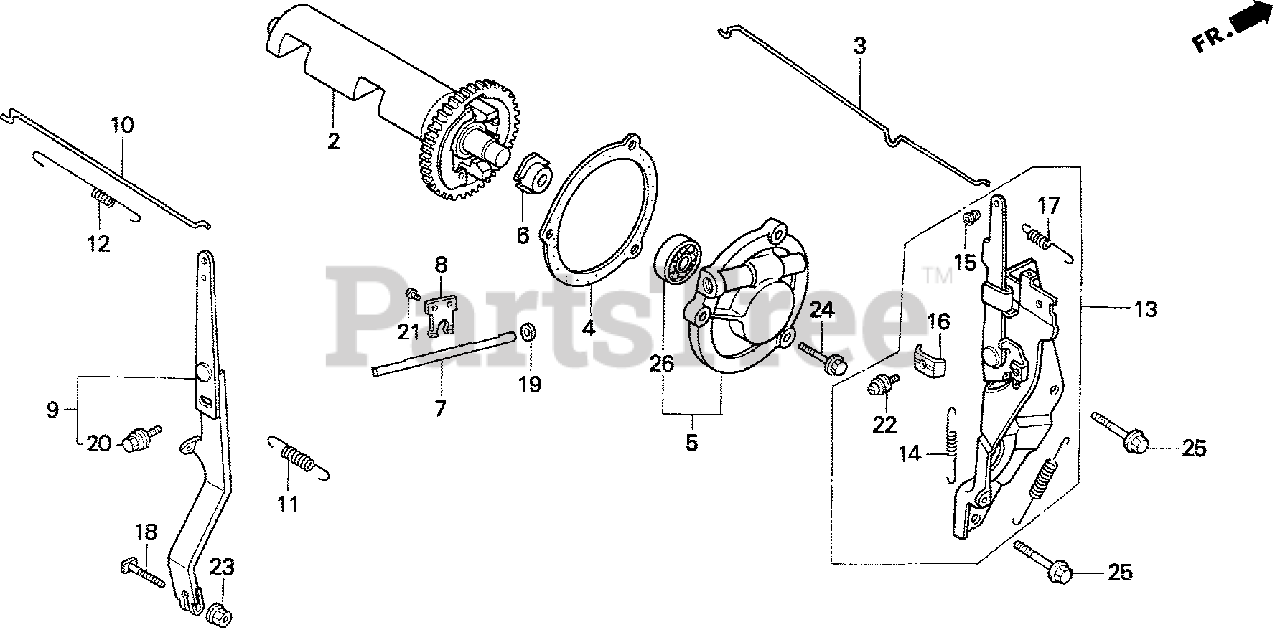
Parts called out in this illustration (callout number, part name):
2	WEIGHT, BALANCER
3	ROD, CHOKE
4	GASKET, GOVERNOR COVER
5	COVER, GOVERNOR
6	SLIDER, GOVERNOR
7	SHAFT, GOVERNOR ARM
8	FORK, GOVERNOR
9	ARM, GOVERNOR
10	ROD, GOVERNOR
11	SPRING, GOVERNOR
12	SPRING, THROTTLE RETURN
13	CONTROL
14	SPRING, CONTROL LEVER RETURN
15	COLLAR, LEVER
16	HOLDER, CABLE
17	SPRING, CABLE RETURN
18	BOLT, GOVERNOR ARM
19	OIL SEAL (8X14X5)
20	BOLT-WASHER (6X12)
21	SCREW, PAN (3X8)
22	SCREW, PAN (5X16)
23	NUT, FLANGE (6MM)
24	BOLT, FLANGE (6X25)
25	BOLT, FLANGE (6X45)
26	BEARING, RADIAL BALL (6202)
